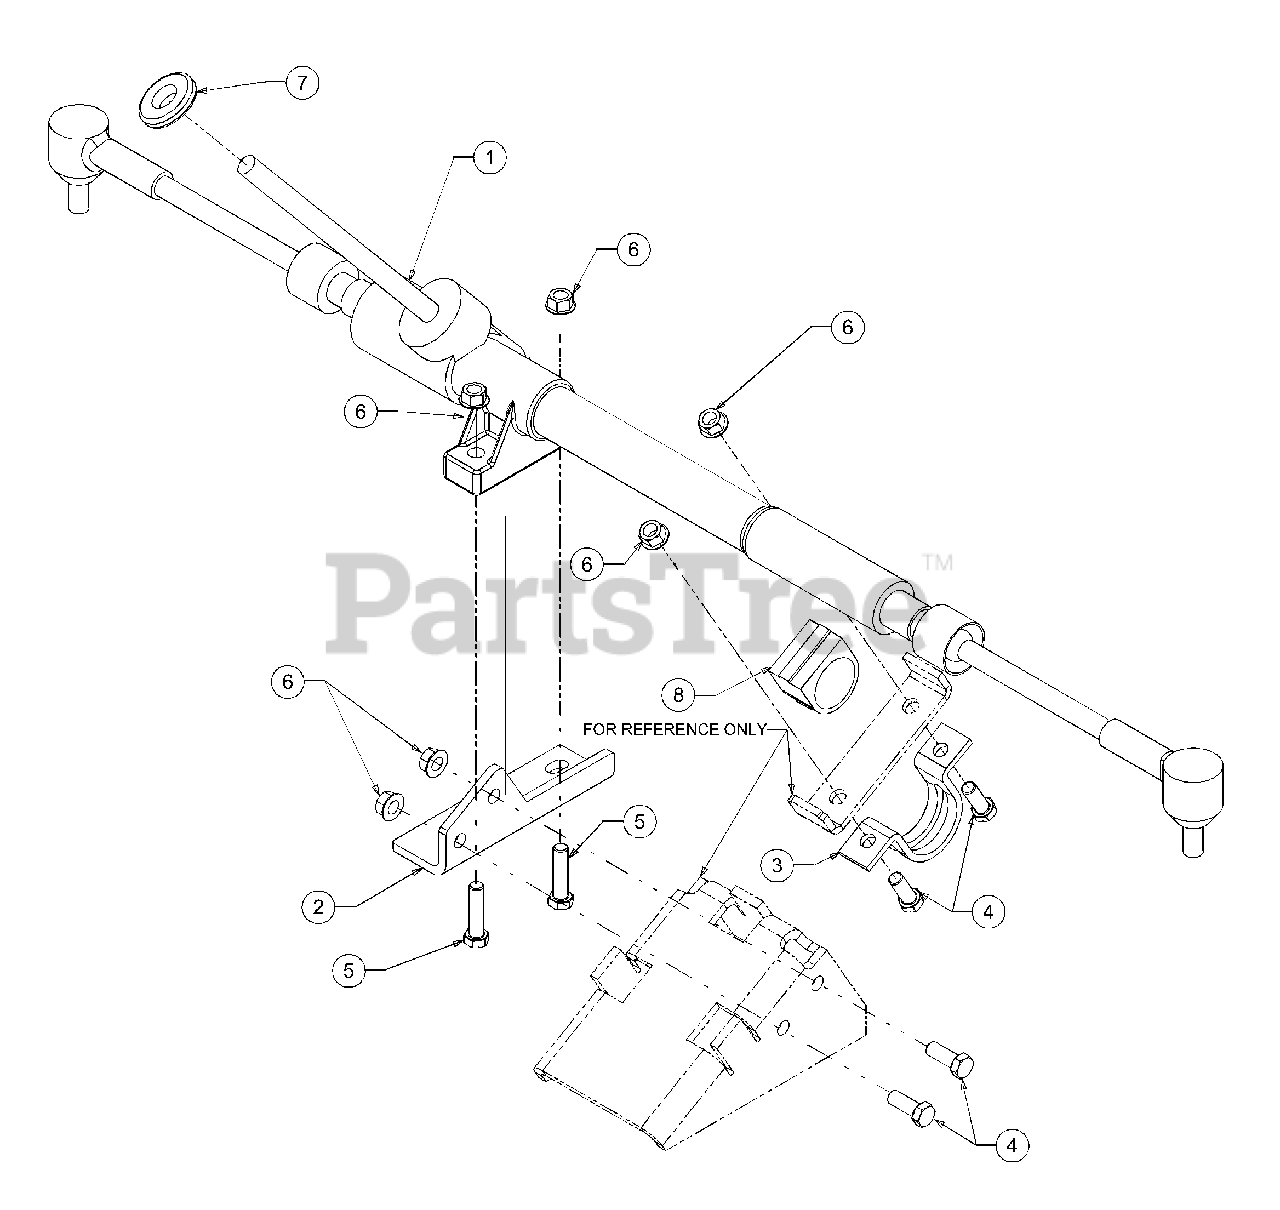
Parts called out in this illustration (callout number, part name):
1	Gear Assembly, Steering
4	Hex Screw, 3/8-16, 1.00, Gr5
5	Hex Screw, 3/8-16, 1.50, Gr5
6	Nut, Flange Lock, 3/8-16
7	Grommet, Steering Shaft
8	Bushing, Rubber
